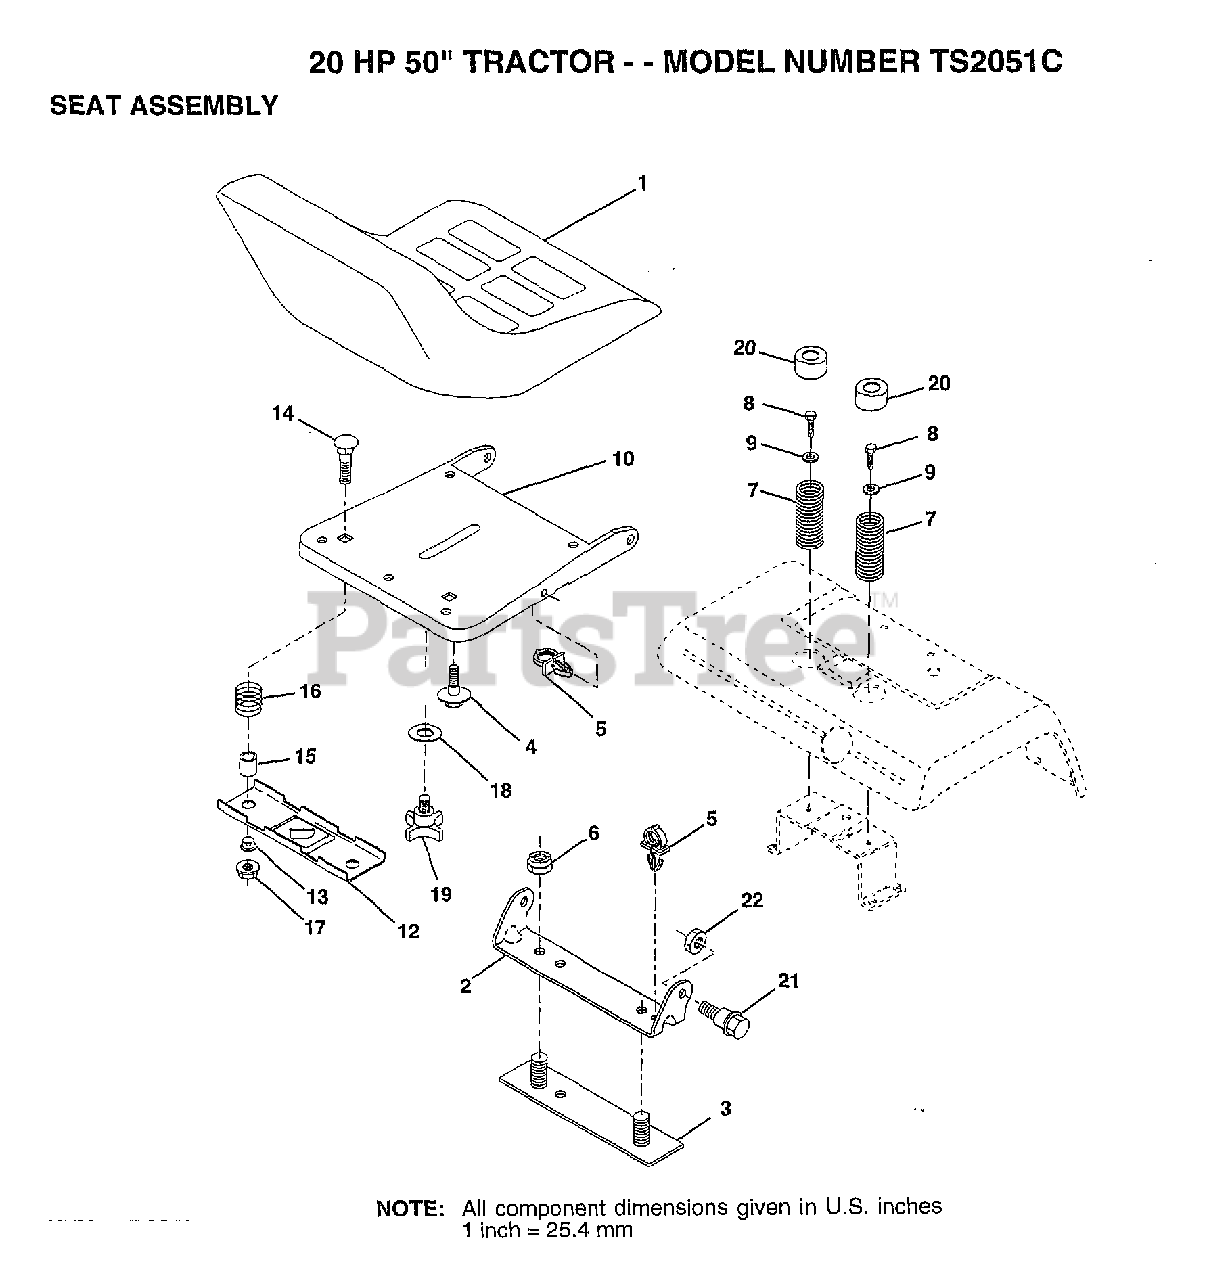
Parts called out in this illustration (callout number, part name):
2	BRACKET PVT SEAT
3	STRAP ASM FENDER
4	"BOLT,SHOULDER"
5	CLIP PUSH - IN
6	NUT
7	SPRING COMPRESSIO
8	SCREW LT
9	WASHER
12	BRKT SWITCH
13	BUSHING
15	SPACER SPLIT
16	SPRING COMPRESSED
18	WASHER
19	"KNOB 1/2"" YT"
20	CAP SPRING
21	BOLT.SHLD.5/16-18
